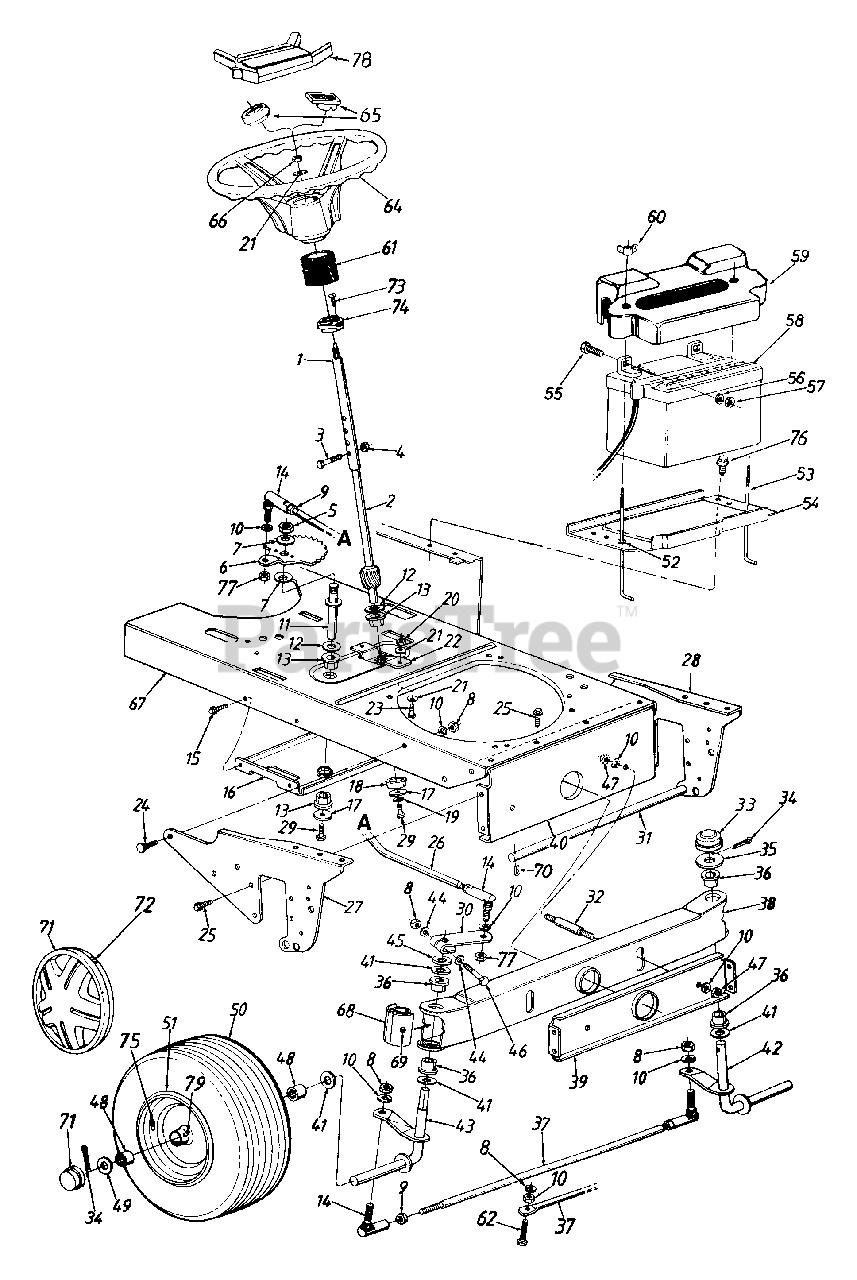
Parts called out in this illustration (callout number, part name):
1	Steering Column Ass'y.
2	Lower Steering Shaft
3	Hex Bolt 1/4-20 x 1.31" Lg.
4	Hex L-Nut 1/4-20 Thd.
5	Hex Jam Nut 5/8-18 Thd.
6	Steering Gear Segment
7	Bell-Wash. 5/8" I.D. x 1.25" O.D.
8	Hex Nut 3/8-24 Thd.
9	Hex Jam Nut 3/8-24 Thd.
10	L-Wash. 3/8" I.D.
11	Steering Gear Segment Shaft
12	Fl-Wash. .64" I.D. x 1.24" O.D.
13	Hex Flange Brg. .63" I.D.
14	Ball Joint Ass'y.
15	Hex Wash. Hd. TT-Tap Scr. 1/4-20 x .5" Lg.
17	Fl-Wash. .33" I.D. x 1.25" O.D.
18	Spacer .985" I.D. x 1.25" O.D.
19	L-Wash. 5/16" I.D.
20	Hex Nut 5/16-24 Thd.
21	Bell-Wash. .345" I.D. x .88" O.D.
24	Ribbed Neck Bolt 3/8-24 x .8" Lg.
25	Hex Wash. TT-Tap Scr. 5/16-18 x .62" Lg.
26	Steering Drag Link
27	Pivot Bar Side Plate - R.H.
28	Pivot Bar Side Plate - L.H.
29	Hex Bolt 5/16-18 x .62" Lg.
30	Steering Arm
31	Deck Connecting Rod
32	Pivot Bar Shld. Bolt 3/8-16 x 5/8" Lg.
33	Cap
34	Cotter Pin 5/32" Dia.
35	Flat Washer
36	Flange Brg..757" I.D.
37	Tie Rod 20.25" Lg. (Adjustable)
38	Pivot Bar Assy.
41	Fl-Wash..76" I.D. x 1.49" O.D.
42	Front Axle Ass'y.- L.H.
43	Front Axle Ass'y.- R.H.
44	Bowed Washer
45	Spacer .755" I.D. x 1.25" O.D.
46	Hex Bolt 3/8-24 x 2.25" Lg.
47	Hex Nut 3/8-16 Thd.
48	Bearing
49	Fl-Wash. .71" I.D. x 1.5" O.D.
53	Battery Hold Down Rod
54	Battery Plate
56	L-Wash. 1/4" I.D.
57	Hex Nut 1/4-20 Thd.
58	Battery (275 Cold Crank Amps)
59	Battery Cover
60	Wing Nut Plastic 1/4-20 Thd.
61	Steering Bellow
62	Hex Bolt 3/8-24 x 1.5" Lg. (Gr. 5)
64	Steering Wheel (3 Spoke)
65	Steering Wheel Cap (Round)
66	Hex L-Nut 5/16-24 Thd.
69	Grease Fltting
70	Internal Cotter Pin
71	Hub Cap
72	Spring Clip
73	Oval Hd. Cr.- Sunk Scr. #10 x 5/8" Lg.
74	Flange Brg. .89" I.D. x 1.36" O.D.
75	Air Valve
76	Hex AB-Tap Scr. 1/4 x .62" Lg.
77	Hex Jam L-Nut 3/8-24 Thd.
78	Steering Wheel Insert
79	Grease Fltting
